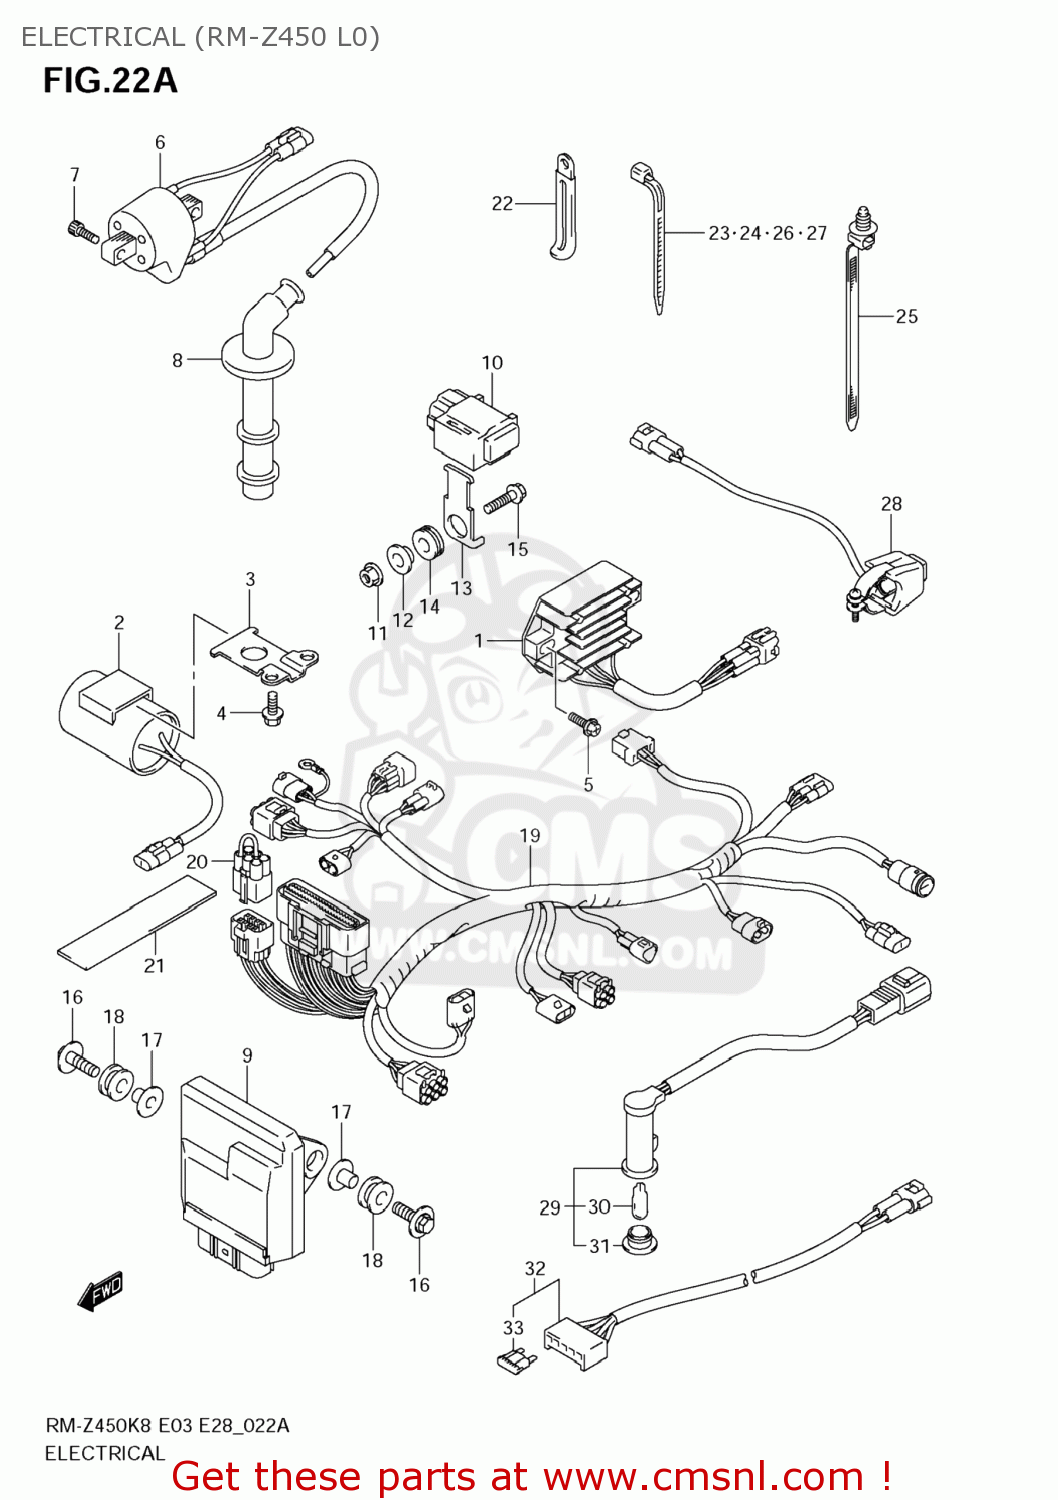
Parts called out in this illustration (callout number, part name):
1	RECTIFIER ASSY
2	CONDENSER ASSY
3	BRACKET,CONDENSER
4	BOLT(6X10)
5	SCREW
6	COIL ASSY,IGNITION
7	BOLT
8	CAP ASSY,SPARK PLUG
9	CONTROL UNIT,FI
10	SENSOR ASSY,FUEL CUT
11	NUT
12	SPACER(6.2X8.4X10.9)
13	BRACKET,FUEL CUT SENSOR
14	CUSHION
15	BOLT
16	BOLT(6X20)
17	SPACER(6.2X8.4X10.9)
18	GROMMET
19	HARNESS,WIRING
20	WIRE,SHORT
21	COVER,HARNESS
22	CLAMP(L:45)
23	CLAMP(L:95)
24	CLAMP(L:125)
25	CLAMP(L:154)
26	CLAMP(L:165)
27	CLAMP(L:235)
28	SWITCH ASSY,ENGINE STOP
29	LAMP ASSY,FI INDICATOR
30	BULB(12V3.4W,T10)
31	LENS(RED)
32	WIRE,BATTERY
33	FUSE(10A)
